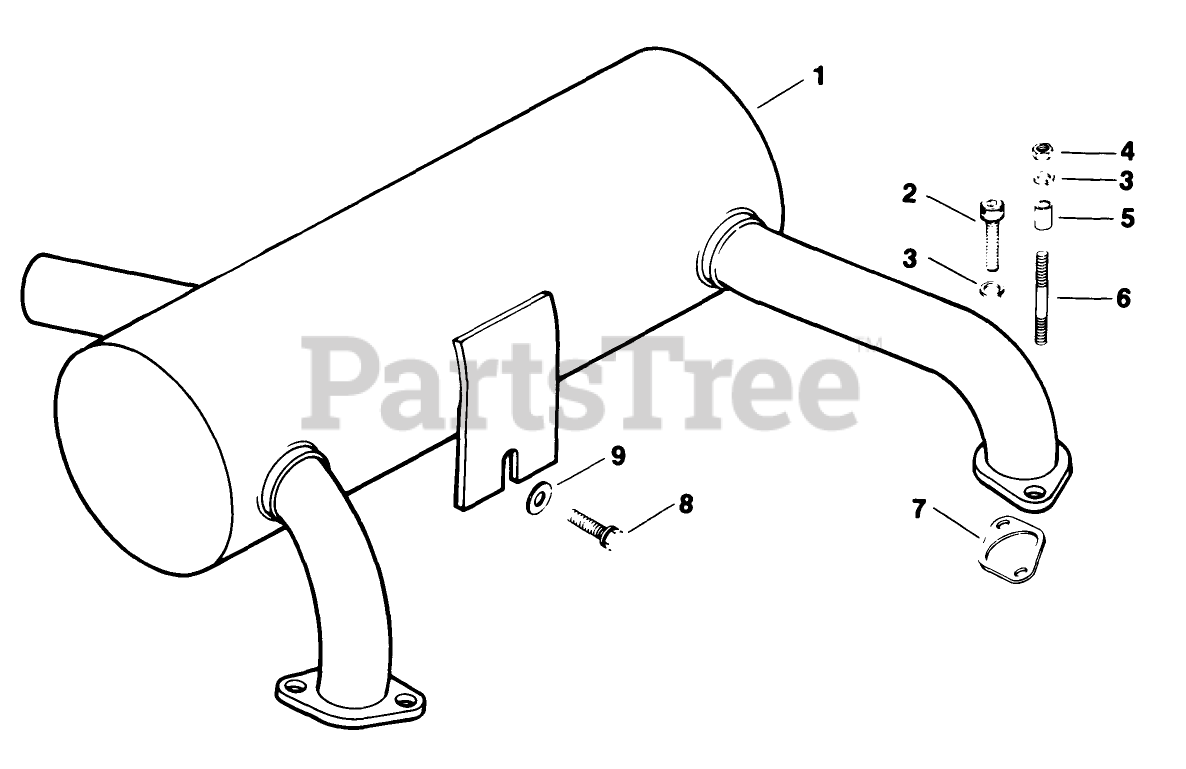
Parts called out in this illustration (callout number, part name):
1	Muffler
2	Screw
3	Washer
4	Nut
7	Gasket Exhaust
8	Screw
9	Washer
